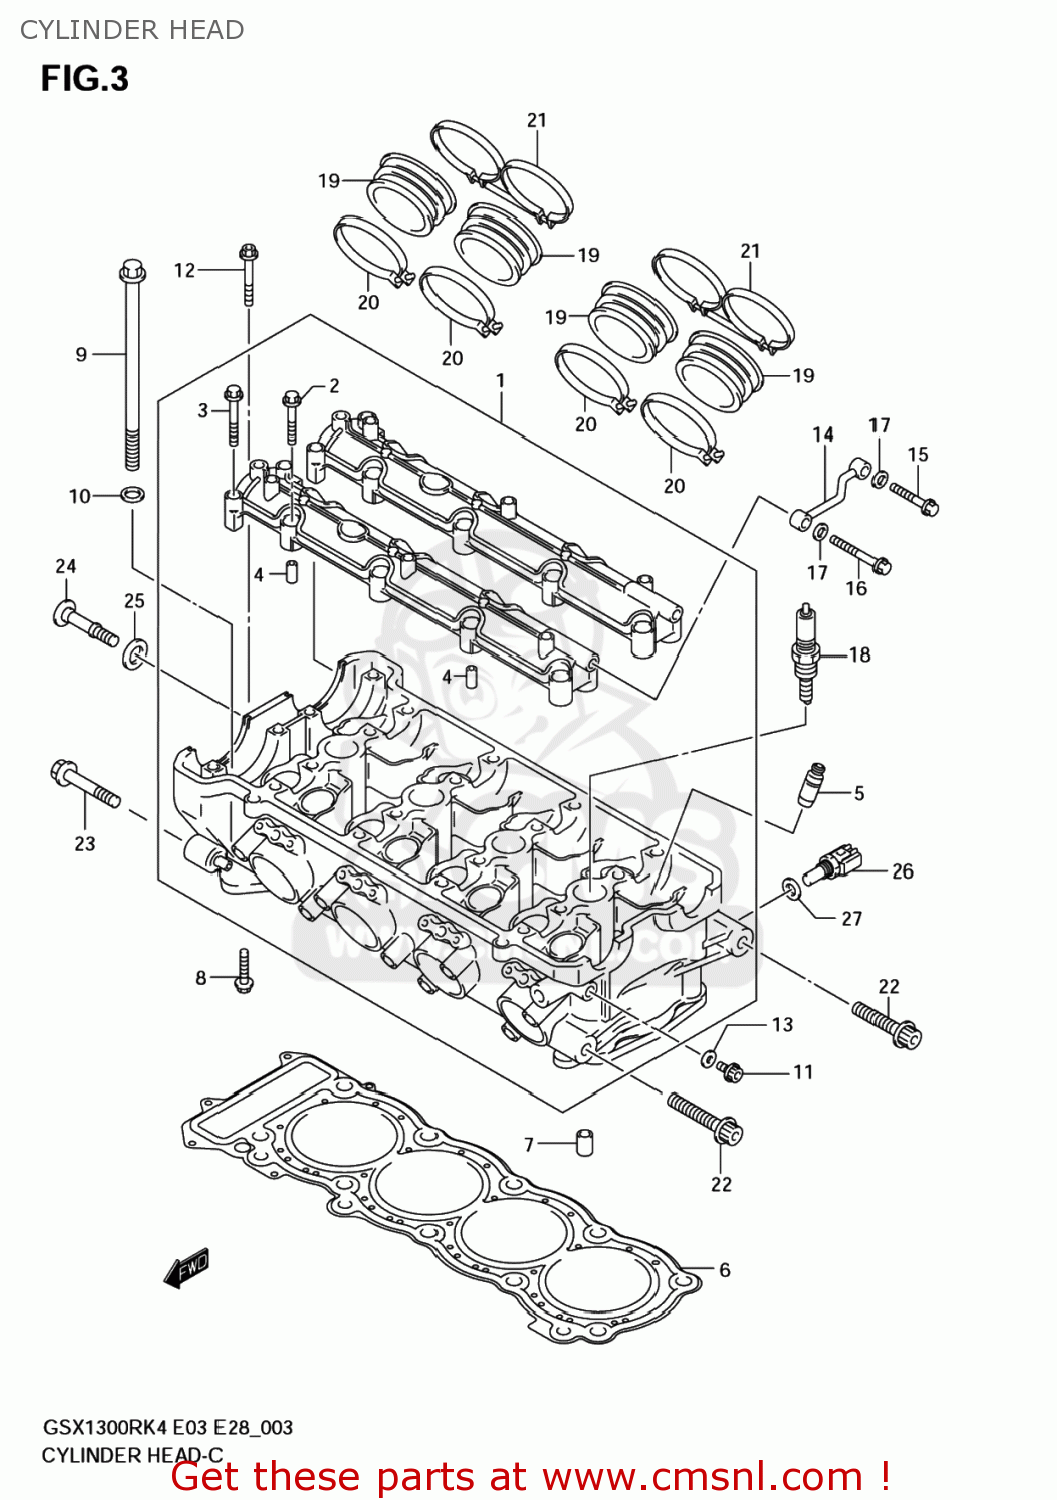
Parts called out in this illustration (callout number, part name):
1	HEAD ASSY,CYLINDER
2	BOLT(6X39)
3	BOLT(6X45)
4	PIN(6.2X8X16)
5	GUIDE,VALVE
6	GASKET,CYLINDER HEAD (NAS)
7	PIN
8	BOLT
9	BOLT(10X175)
10	WASHER(10.5X19X2)
11	BOLT(6X12)
12	BOLT,CYL.OIL P
13	GASKET(5.8X13X1.2) (NAS)
14	PIPE,CYLINDER HEAD OIL
15	BOLT
16	BOLT (6X45)
17	WASHER
18	PLUG,SPARK(CR8E)
19	PIPE,INTAKE
20	CLAMP
21	CLAMP,INTAKE P
22	BOLT
23	BOLT
24	BOLT,CYL HEAD SIDE FACE
25	WASHER,HEAD COVER
26	SENSOR,WATER TEMP
27	GASKET(12X17X1) (NAS)
